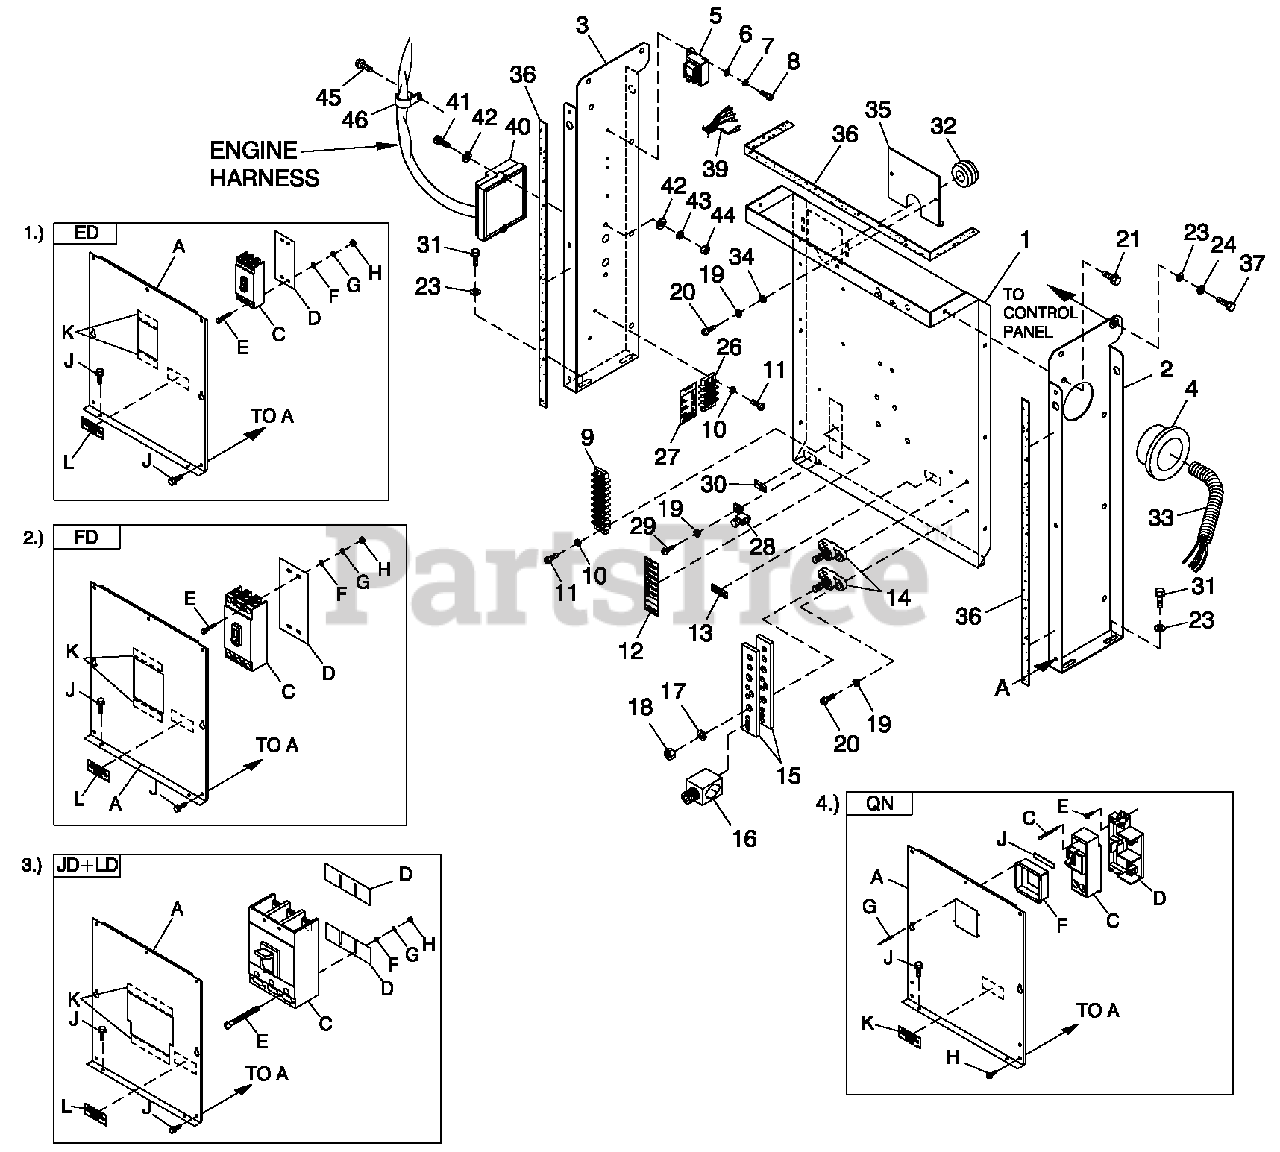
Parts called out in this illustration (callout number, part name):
1	PAN CBCONN BOX
1	UL CIRCUIT BREAKER(ED)
2	STAND RH CONTROL
2	UL CIRCUIT BREAKER(FD)
3	STAND LH CONTROL
3	UL CIRCUIT BREAKER(JD+LD)
4	BUSHING SNAP SB-2.5-31
4	UL CIRCUIT BREAKER(QN)
5	XFMR DUAL 120V/16V (FOR 120/240V & 277/480V UNITS)
6	WASHERFLAT M4
7	WASHERLOCK #8-M4
8	SCREW PHTT M4-0.7 X10ZYC
9	BLOCKTE RM 20A8 X 6 X1100V
10	WASHERLOCK #6
11	SCREW PHTT #6-32 X 1/2Z YC
12	DECAL UT L SENSE/CUST CONN
13	DECAL ^U T R A L
14	JUNCTION BLOCK 3/8-16
15	BUS BAR NEUTRAL BLOCK 390
16	LUG SLDLSS 600/250-1/0 X 1/4-28
17	WASHERLOCK 3/8
18	NUT H E X 3/8-16 STEEL
19	WASHERLOCK M5
20	SCREW PHTT M5-0.8 X 16ZYC
21	SCREW THFM6-1X 16N WAZ/JS
23	WASHERFLAT 1/4-M6ZINC
24	WASHERLOCK M6-1/4
26	BLOCKTE RM 20A6 X 3 X1100V
27	DECAL CUST CONN 120V UTILITY
28	LUG SLDLSS#6-14X13/64 CU
29	SCREW HHTT #10-32 X 3 /8C Z
30	DECAL GROUND LUG
31	SCREW HHTT M6-1.0 X 16ZYC
32	GROMMET 1.25X .25 X .75
33	CONDUIT FLEX 2.0' ID (36" LG)
34	WASHERFLAT M5
35	PLATE WIRE SNGLGALV
36	TAPE ELEC 1/2 FOAM (AS REQ'Q
37	SCREW HHC M6-1.0X 16G8.8
39	HARNESS, TRANSFORMER ADAPTER
40	ASSY ENCLOSURE PCB 4.2L IGN MD
41	SCREW PPHM #10/32X2
42	WASHERFLAT # 1 0ZINC
43	WASHERLOCK #10
44	NUT HEX#10-32 STEEL
45	SCREW THF M6-1 X 1 6 N WAZ/JS
46	CLAMP VINYL 1.06 X .406 Z
47	SEALWEATHER.45' DIA
A	COVERED CB SHORT STND
C	CB0050A3P 480V S ED4 LL
D	INSULATOR CBS (ED-3 P)
E	SCREW RHM #10-32X4-1/2
F	WASHERFLAT # 1 0ZINC
G	WASHERLOCK #10
H	NUT HEX#10-32 STEEL
J	SCREW THF M 6-1 X 16 NWAZ/JS
K	TAPE ELEC 1/2 FOAM (AS REQ'D)
L	DECAL CUSTOMER CONNECT INSIDE
A	COVERCBCONN BOX
C	CB0150A3P 600VS FD6LL
D	INSULATOR CB FD FRAME 30ML
E	SCREW SHC1/4-20X 4.5 G8.8NZ
F	WASHERFLAT 1/4-M6ZINC
G	WASHERI OCK MR. 1/4
H	NUT HEX 1/4-20 STEEL
K	TAPE ELEC 1/2 FOAM (AS REQ'Q
A	COVER JD/LD SHRT STAND
C	CB 0300A 3P 600V S JD6LL
D	INSULATOR CIRCUIT BR. JD/LD
E	SCREW RHM 1/4-20X3
F	WASHER FALT 1/4-M6 ZINC
G	WASHER LOCK M6-1/4
H	NUT HEX 1/4-20STEEL
J	SCREW THF M6-1 X 1 6 N WAZ/JS
A	COVER QN FRM CB
C	CB 0300A 2P 240V S QN2LL
D	BASE, QN CIRCUIT BREAKER
E	SCREW HHTT M65-0.8X10BP
F	COVER QN CB DISH
G	RIVET POP 125X 275 SS
H	SCREW THF M6-1X16 N WA Z/JS
J	TAPE ELEC 1/2 FOAM (AS REQ'D)
K	DECAL CUSTOMER CONNECT INSIDE
